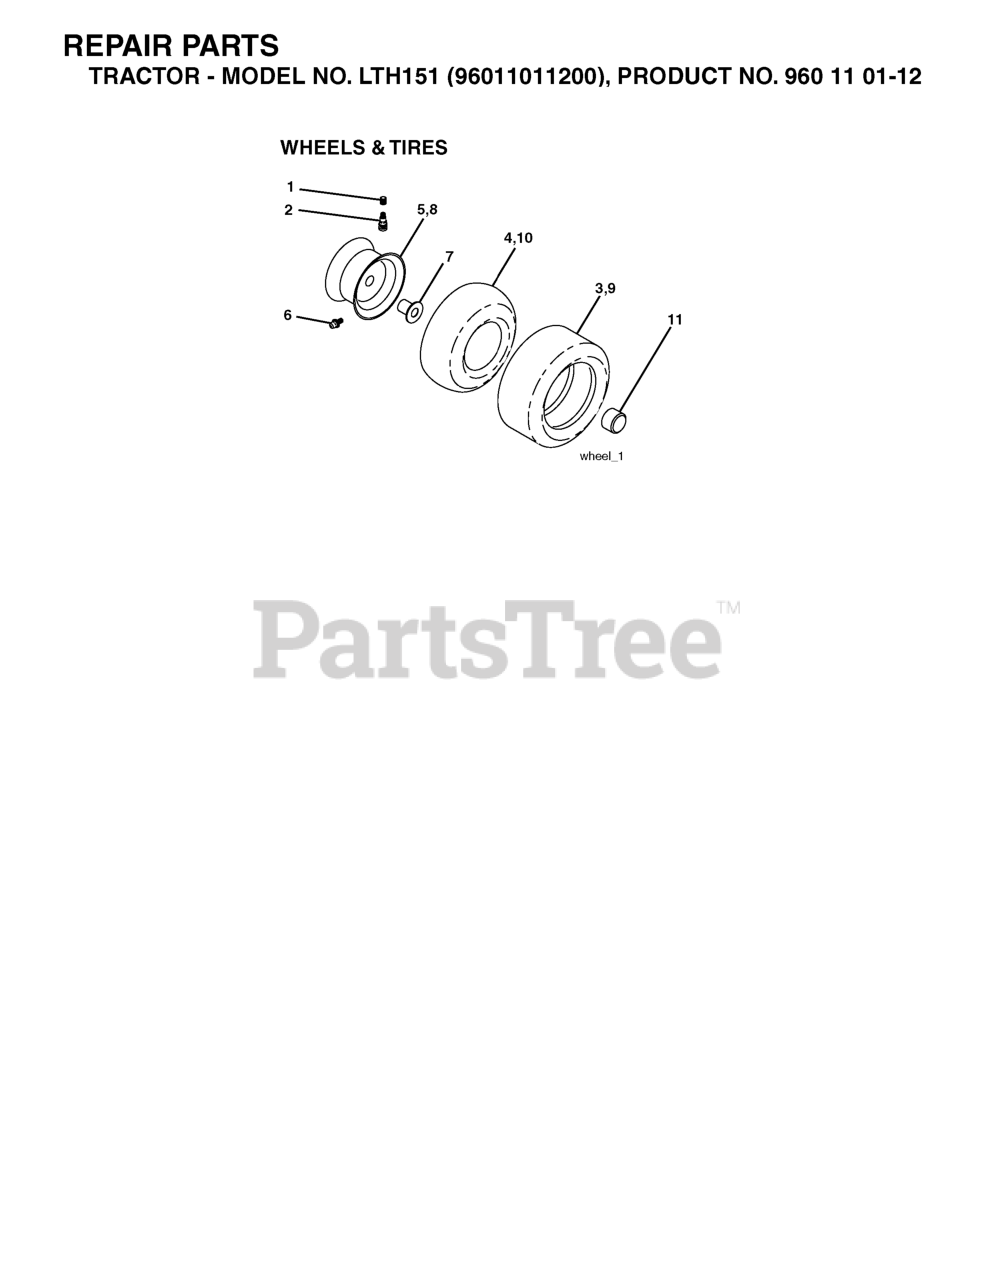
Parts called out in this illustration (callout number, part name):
2	VALVE STEM LT
3	TIRE HEAVY DUTY
4	TUBE.5.3/4.5/6
5	RIM ASM 6" FRONT SILVER
6	FITTING LT
7	BEARING T
8	RIM ASM 8" REAR SILVER
9	TIRE HEAVY DUTY
10	TUBE
11	CAP, AXLE BLK
